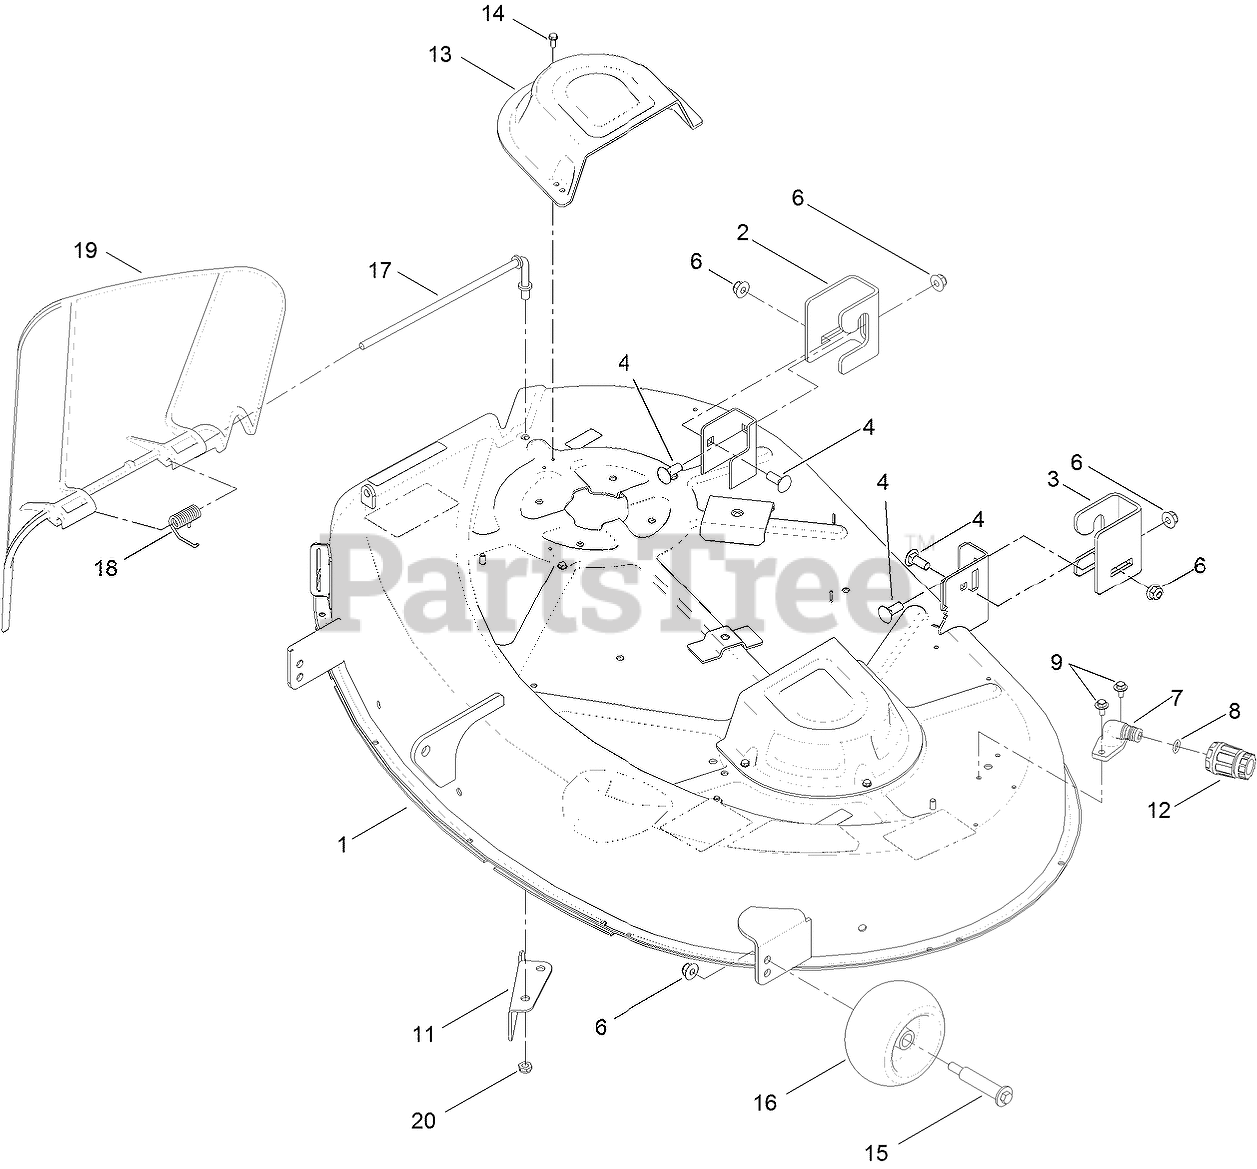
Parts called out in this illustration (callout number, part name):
1	42 INCH DECK AND DECAL ASM
2	BRACKET-HANGER, RH
3	BRACKET-HANGER, LH
4	BOLT-CARR
6	NUT-HF, NI
7	FITTING-WASHOUT
8	O-RING
9	SCREW-HHFTF
11	BAFFLE-CUTOFF
12	CONNECTOR-HOSE
13	COVER-BELT
14	SCREW-TAPTITE
15	BOLT-SHOULDER
16	ROLLER-SCALP, ANTI
17	ROD-PIVOT
18	SPRING-TORSION
19	DEFLECTOR
20	NUT-LOCK, NI
